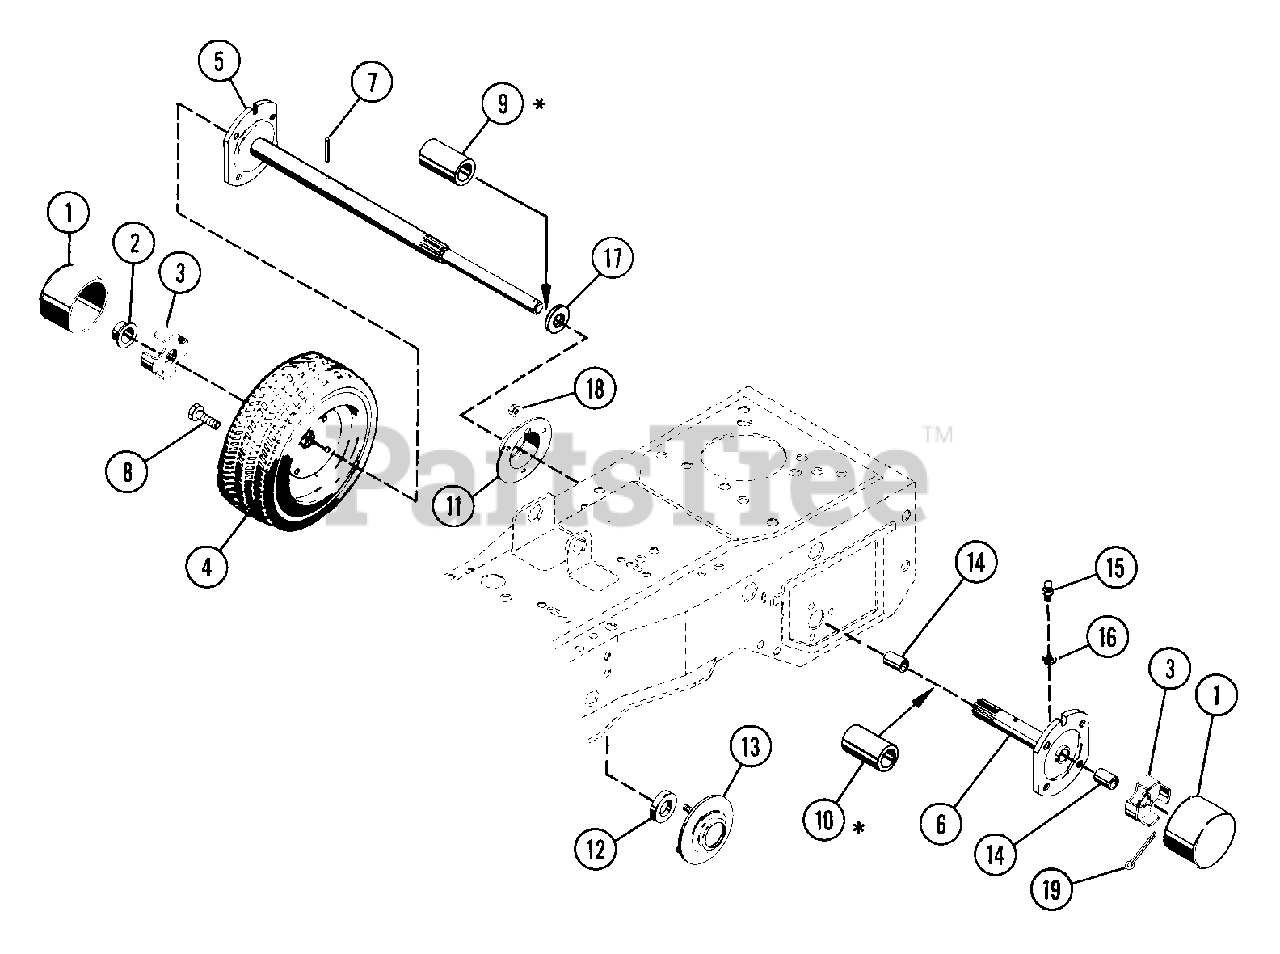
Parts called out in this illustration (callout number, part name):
1	HUB CAP
2	PUSHNUT
3	SPINDLE CUP
4	WHEEL ASSEMBLY
4	TIRE
4	WHL
4	TERRA TIRE & WHEEL ASSEMBLY
4	TIRE 16X6.50-8 2 PLY
5	R H AXLE
5	RH AXLE
6	L H AXLE ASSEMBLY
7	PIN-ROLL .188X1.25
8	BLT-WHL .50-20X.75 GR5 PL
9	TUBE .875 X 1.875 X 4.500
9	TUBE
10	TUBE 1.125 X 1.875 X 4.500
10	TUBE
11	BEARING FLANGE
12	BRG-BALL .876 X 1.750 X .50
13	BEARING FLANGE
14	BSHG-SLV .690X.814X1.000 BR
15	SPIN DRIVE ZERK FITTING
16	WSHR-LK .250X.047 LT PL
17	WSHR-FL-STL .880X1.380X.062
18	NUT-LK-FLG .250-20 PL
19	PIN-COTR .12X1.0 PL
